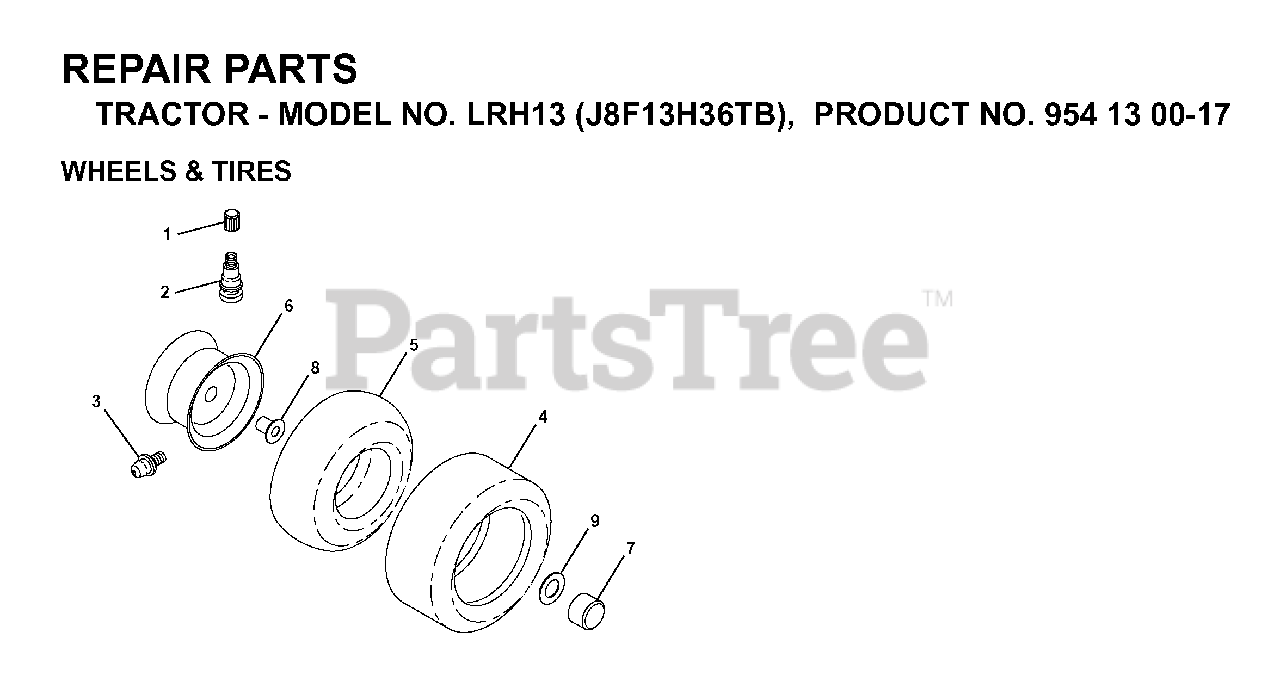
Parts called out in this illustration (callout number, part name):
1	VALVE CAP
2	VALVE STEM LT
3	FITTING LT
4	TIRE FRONT 15X6-6
4	REAR TIRE
5	TUBE.5.3/4.5/6
5	TUBE.16X6.5/7.5-8
6	RIM
6	RIM REAR 8"
7	CAP-HUB FRONT LT
8	BEARING T
